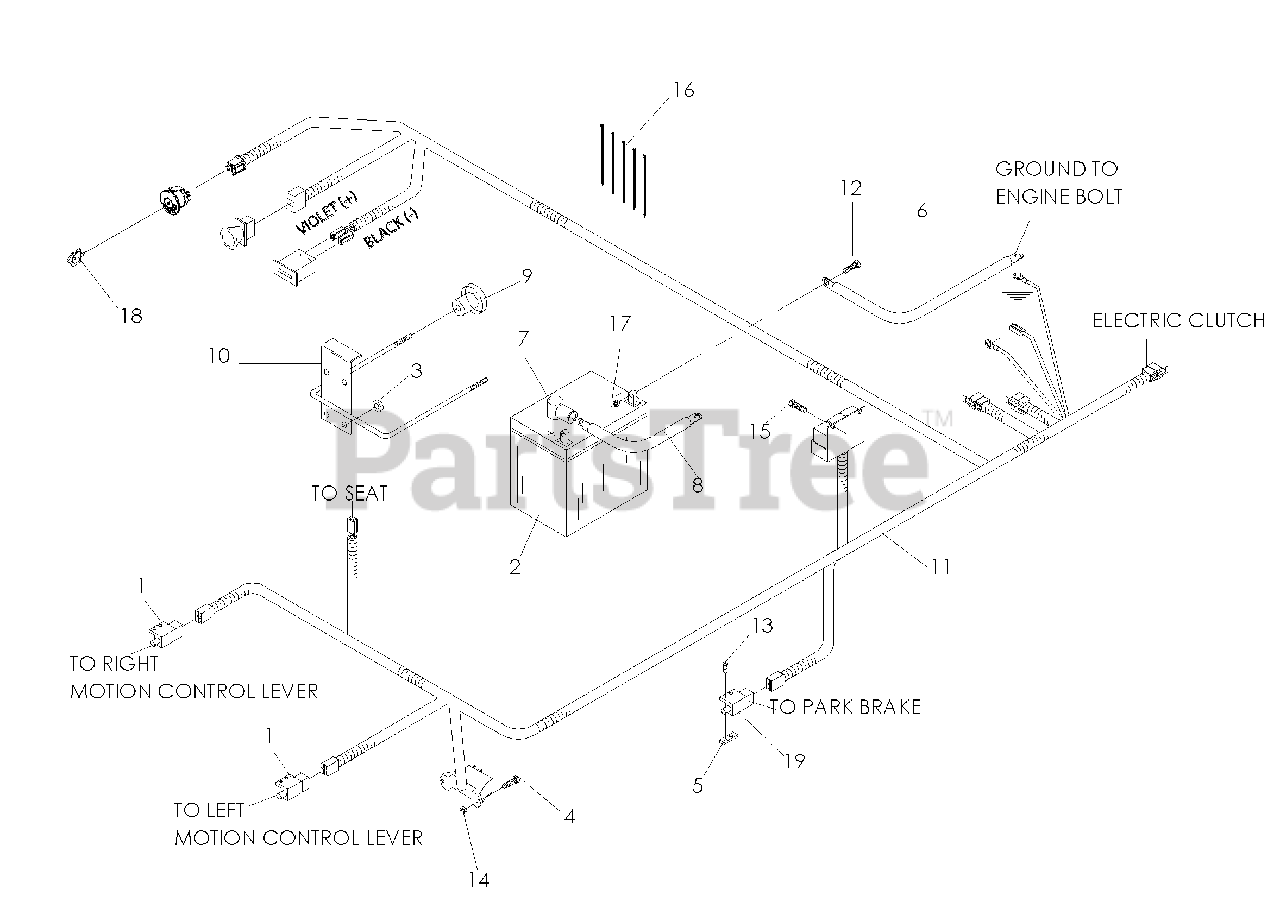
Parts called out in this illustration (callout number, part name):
1	SWITCH, INTERLOCK
2	BATTERY, 12 V 330 AMP TBR
3	GROMMET, BUMPER
4	SCREW, #1--24 X 1/2 SLOTTED
5	TAPPED PLATE
6	CABLE-NEGATIVE
7	INSULATOR
8	POST.CABLE LONG
10	BATTERY HOLD DOWN
11	HARNESS, KODIAK
12	HCS 5/16C X 3/4
13	SCREW #10-24 X 5/8
14	NUT 10-24 NYLOC
15	SCREW #10 X 1/2 SELF TAPPING
16	TIE, PLASTIC
17	HARNESS, WIRING DXK/DXG
18	KEY
19	SWITCH, INTERLOCK
